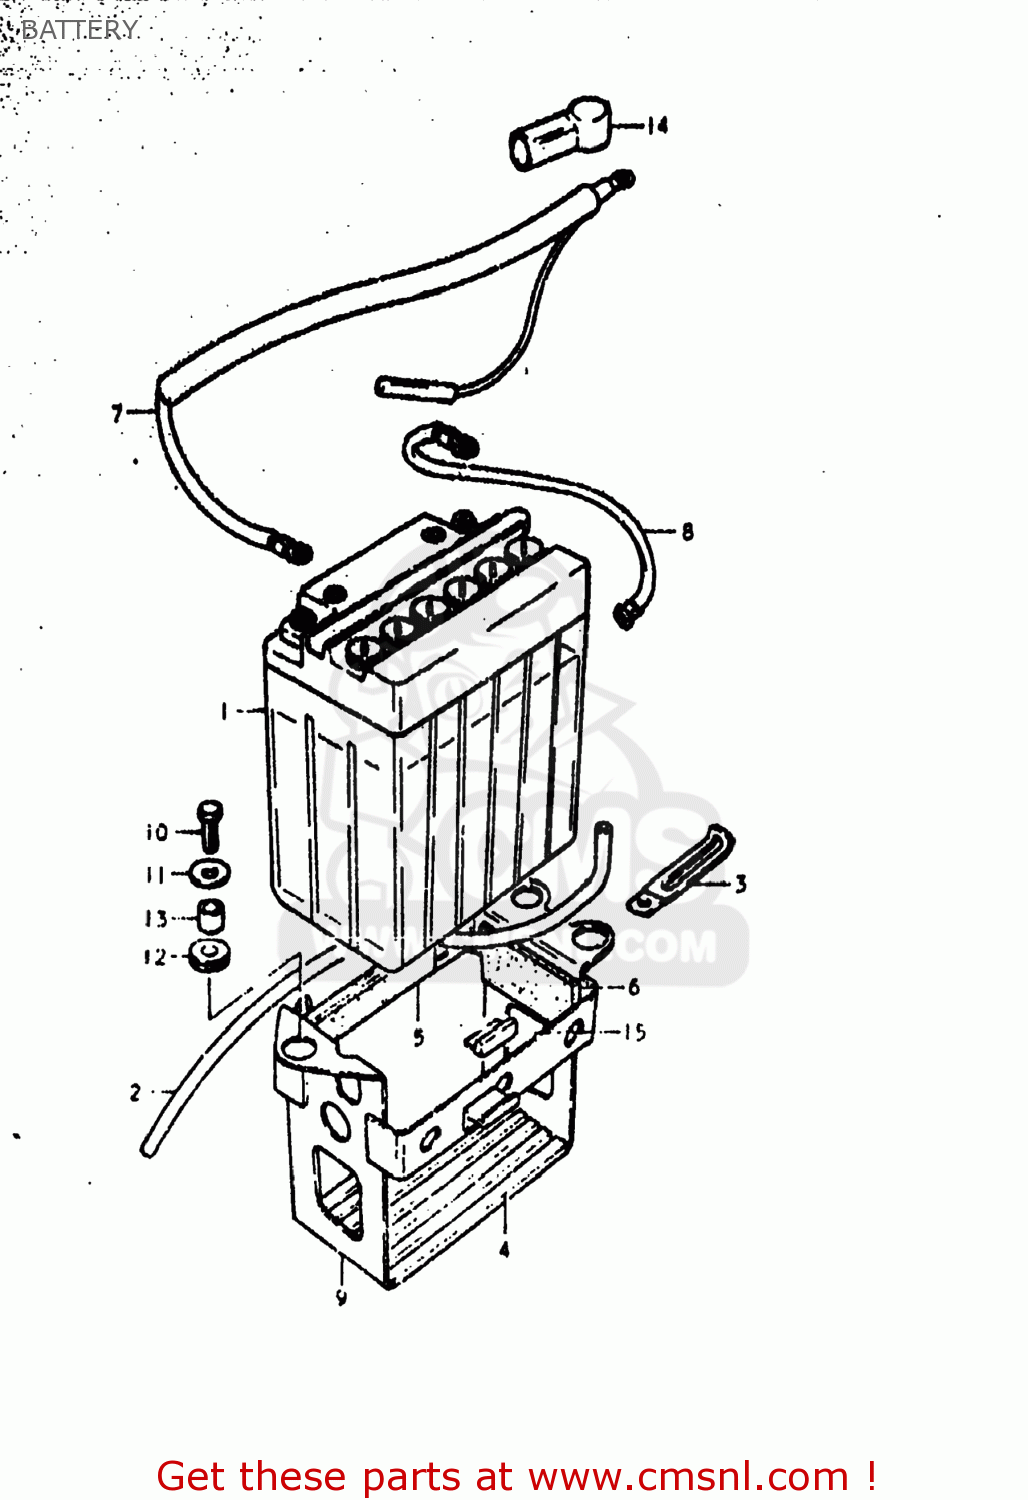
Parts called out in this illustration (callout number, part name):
1	BATTERY ASSEMBLY
2	HOSE,BATTERY EXHAUST
3	CLAMP L:35
4	PROTECTOR,BATTERY
5	PROTECTOR,20X9
6	CUSHION,BATTERY
7	WIRE,BATTERY PLUS
8	LEAD WIRE,BATTERY(-)
9	HOLDER,BATTERY
10	BOLT, UPPER
11	WASHER
12	CUSHION
13	SPACER(6.1X9X7.5)
14	CAP,TERMINAL
15	CUSHION,FRAME COVER
